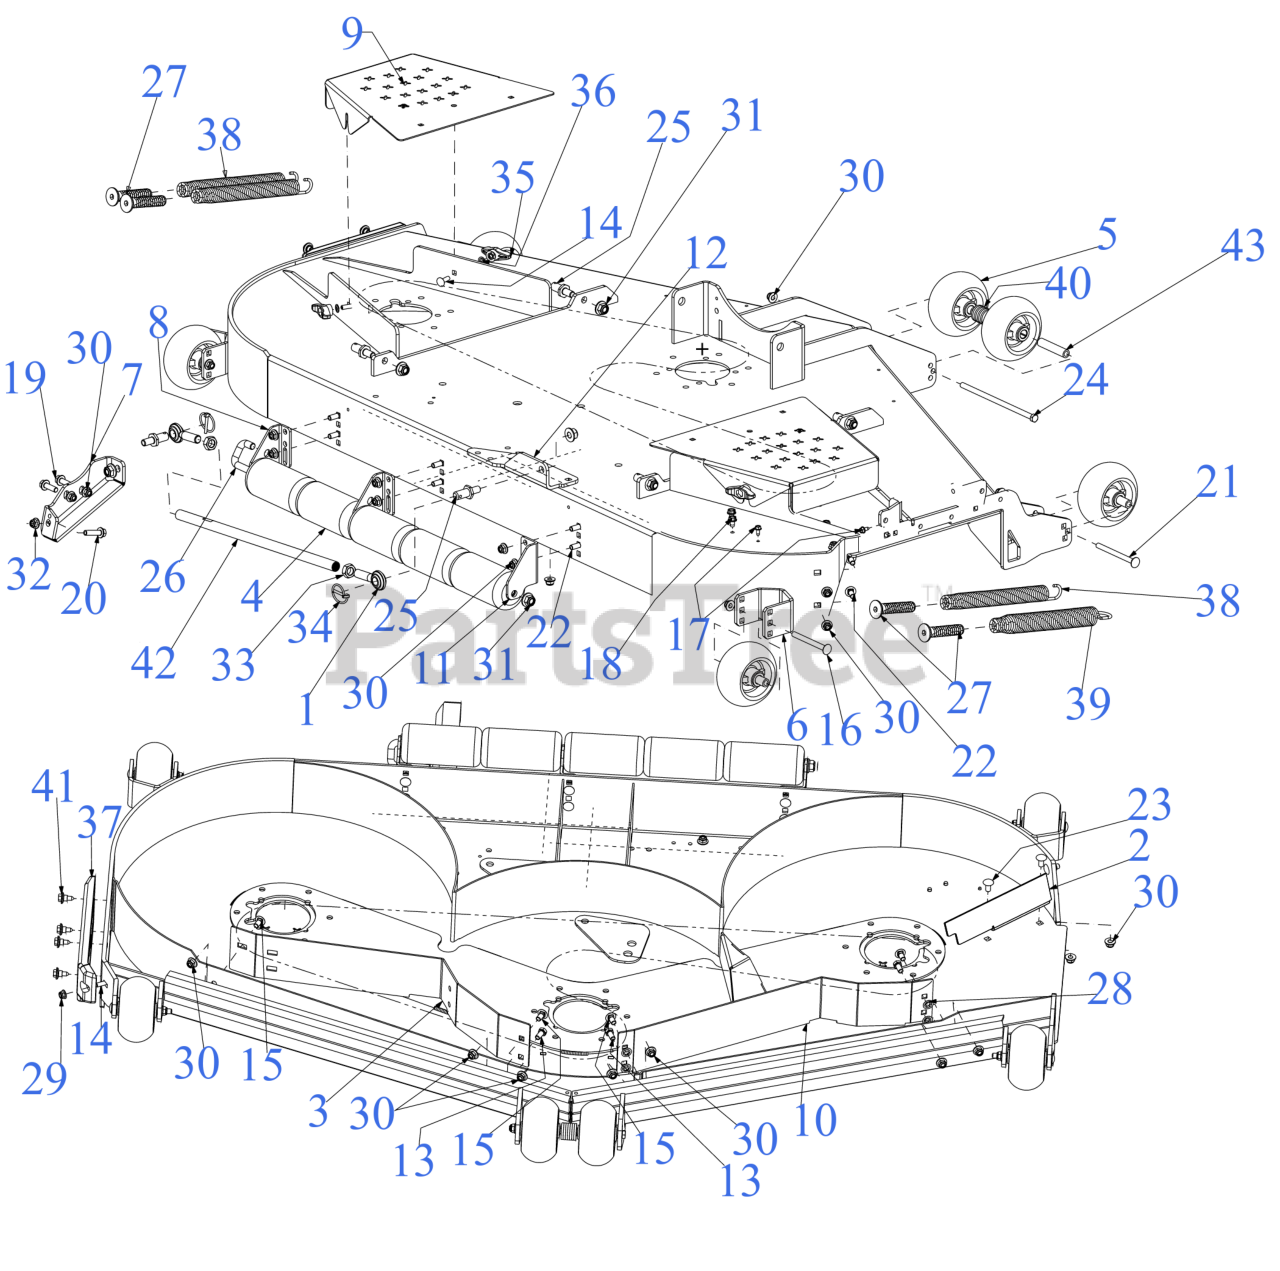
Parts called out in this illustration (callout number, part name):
1	MALE ROD END
2	BAFFLE - CHUTE
3	BAFFLE - 72" ADJ
4	ROLLER ASSEMBLY
4	FLANGE BEARING
5	5" DIA DECK WHEEL COMPLETE
5	FLANGE BEARING
6	72" FAB DECK SHELL
7	STABILIZER MOUNTING BRACKET
8	REAR MOUNT BRACKET
9	BELT COVER
11	REAR ROLLER BRACKET (RH)
12	DECK BELT GUIDE BRACKET
13	HEX SCREW 3/8-16 x .75
14	CARRIAGE BOLT 5/16-18 x 1.00
15	CARRIAGE BOLT 3/8-16 x .750 GR5
16	CARRIAGE BOLT 3/8-16 x 4.00 GR5
17	SCREW 1/4-20 X.500
18	SCREW 5/16-18 x .500
19	SCREW 3/8-16 x 1.25 GR5
20	HEX HEAD BOLT (3/8-16:1.50 GR8)
21	CARRIAGE BOLT 3/8-16 x 4.25 GR5
22	CARRIAGE BOLT 3/8-16 x 1.00 GR5
23	CARRIAGE BOLT 3/8-16 x .75
24	SCREW 3/8-16 x 8.5 GR5
26	REAR ROLLER PIN
27	SPRING INSERT SCREW
29	FLANGE LOCK NUT 5/16-18
32	LOCK NUT (3/8-16)
33	HEX JAM NUT 5/8-18
34	LYNCH PIN .1875
35	WING KNOB 5/16-18
37	DECK SKID PLATE (LH)
38	EXTENTION SPRING 1.20 x 11.35
39	EXTENSION SPRING 1.44 OD x 11.36
40	FLAT WASHER
41	SHOULDER SCREW .43X.29X5/16-18 TT
42	TUBE .565 X .750 X 18.75"LG
43	WHEEL SPACER .38ID x 3.04LG
